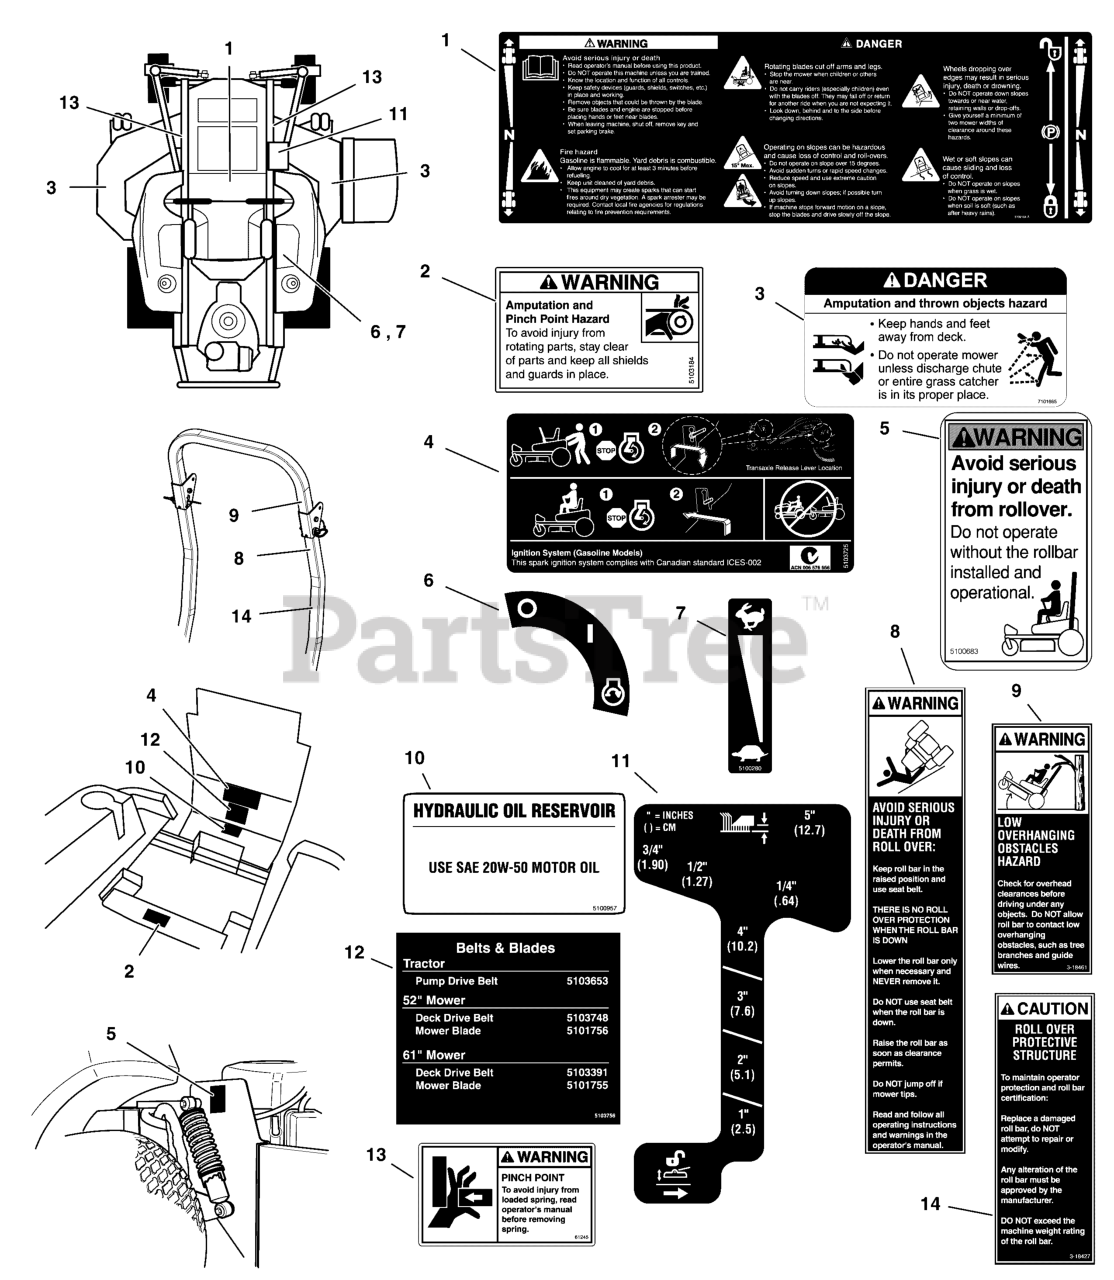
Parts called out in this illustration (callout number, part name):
1	DECAL, Main, Safety, ZT
2	DECAL, WARNING, HAND IN BELT, ENG ONLY
3	DECAL, DANGER DO NOT OPERATE W/O DEFLECT
4	DECAL, TRANSAXLE RELEASE, 600/700
5	DECAL, WARNING, ROLL BAR
6	DECAL, IGNITION SWITCH
7	DECAL, THROTTLE CONTROL
8	DECAL, WARNING, FOLDING ROPS
9	DECAL, WARNING OVERHANG, ROPS
10	DECAL, HYDRAULIC OIL, SAE 20W50
11	DECAL, CUT HEIGHT, IS700/ZTS700
12	DECAL, BELT & BLADE, IS700Z/ZTS700
13	DECAL, PINCH POINT
14	DECAL, CAUTION, FOLDING ROPS
